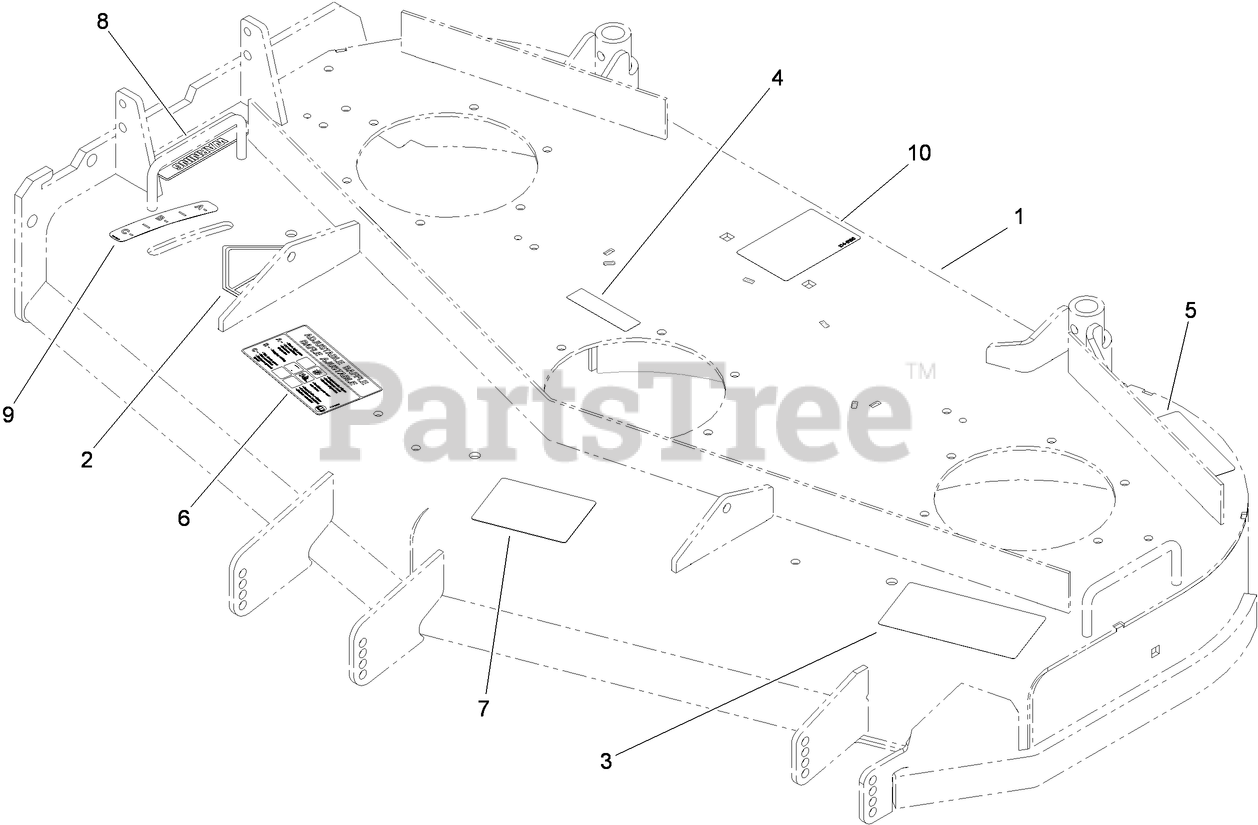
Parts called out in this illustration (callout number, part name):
1	48 INCH DECK ASM
2	DECAL-DANGER
3	DECAL-DANGER, THROWN OBJECT
4	DECAL-COVER, MISSING
5	DECAL-TORQUE
6	DECAL-ADJUSTMENT, BAFFLE
7	DECAL-SCALP, ANTI
8	DECAL-WARNING
9	DECAL-SETTING, BAFFLE
10	DECAL-ROUTING, BELT
